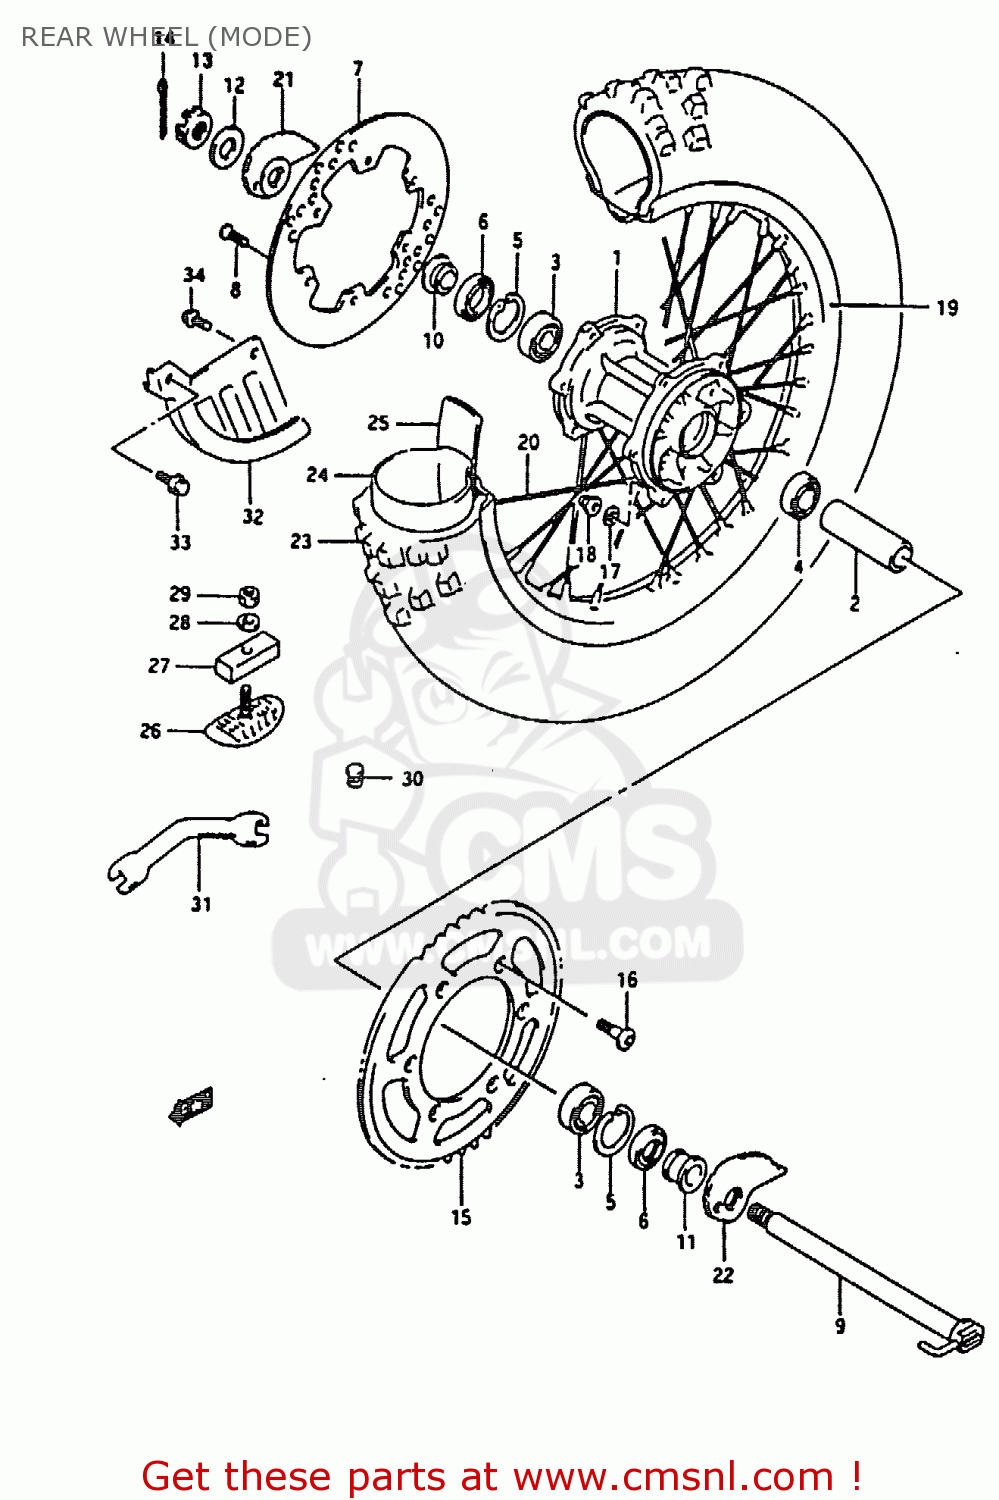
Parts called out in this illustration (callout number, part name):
1	HUB,RR
2	SPACER,RR HUB BEARING
3	BEARING WHEEL REAR(20X47X14)
4	BALL BEARING
5	CIRCLIP,14MM
6	SEAL,OIL(26X47X5)
7	DISC,RR BRAKE
8	SCREW
9	AXLE,RR
10	SPACER,RR AXLE,R
11	SPACER,RR AXLE,L
12	WASHER(19X32X3.2)
13	NUT
14	PIN,COTTER
15	SPROCKET,RR(NT:49)
16	SCREW(8X33.5)
17	WASHER
18	NUT
19	RIM,REAR WHEEL (2.15X18)(A
20	SPOKE ASSY,RR WHEEL
21	ADJUSTER,CHAIN,R
22	ADJUSTER,CHAIN,L
23	TIRE,REAR 110/100-18
24	TUBE ASSEMBLY,WHEEL,INNER
25	PROTECTOR,INNER TUBE
26	STOPPER,BEAD(2.15)
27	CUSHION,BEAD STOPPER
28	WASHER
29	NUT
30	CAP(OD:12)
31	SPANNER,OPEN
32	COVER,REAR DISC
33	BOLT
34	BOLT
